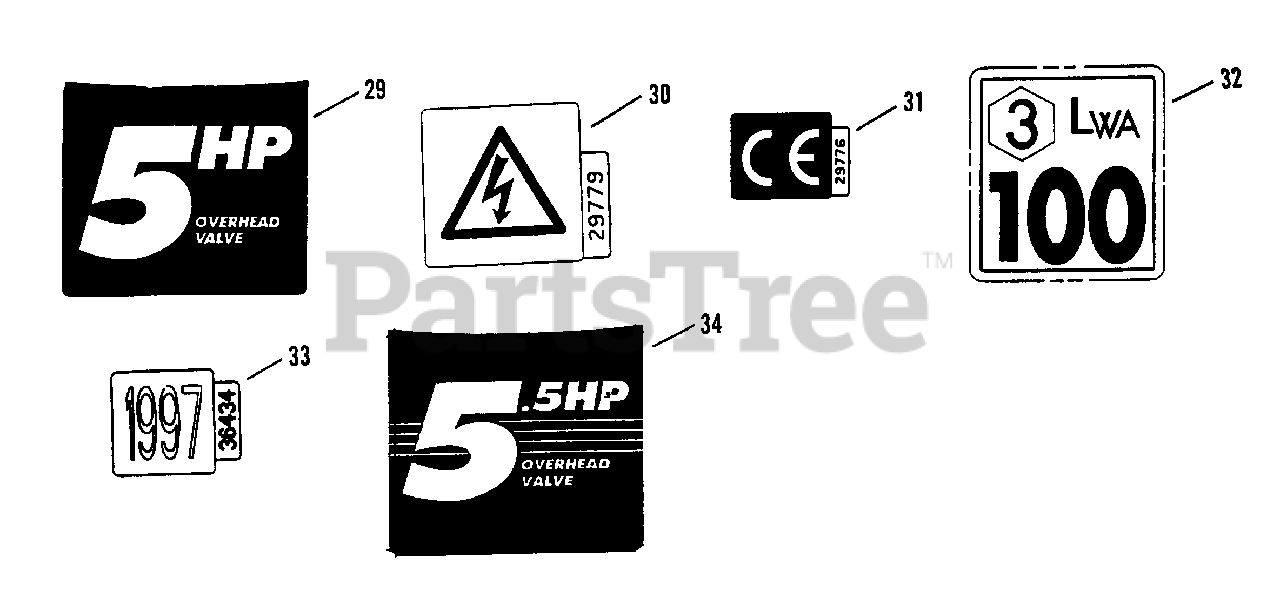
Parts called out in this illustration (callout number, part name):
29	DECAL, Kawasaki Engine 5HP (OHV)
30	DECAL, Spark Plug
31	DECAL, European Community
32	DECAL, Noise Control
33	DECAL, 1997 Year of Manufacture
34	DECAL, 5HP Overhead Valve
